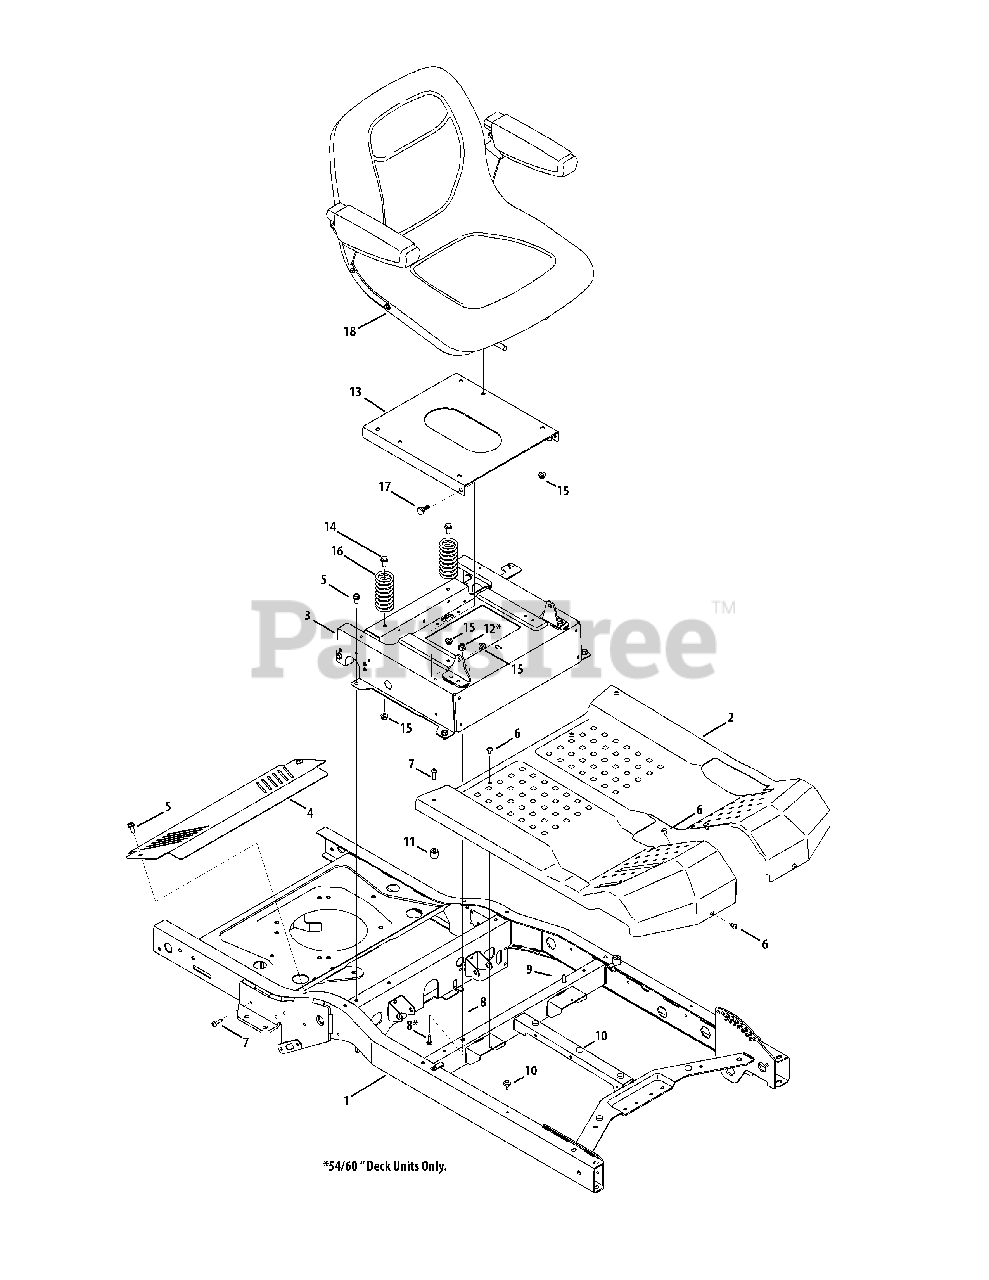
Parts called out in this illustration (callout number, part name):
1	Frame Assembly (46" & 48" Decks)
1	Frame Assembly (54" & 60" Decks)
3	Seat Box Assembly
4	Transmission Cover
5	Hex Washer Screw, 5/16-18 x .750
6	Screw, 1/4-20 x .5
7	Screw, 1/4-20 x 1.0
8	Hex Screw, 1/4-20 x .75
9	Speed Nut, U-Type 1/4-20
10	Rubber Bumper
11	Spacer, .281 x .750 x .680
12	Flange Lock Nut, 1/4-20 (54/60" Deck Units only)
13	Seat Base
14	Hex Washer Screw, 5/16-18
15	Flange Lock Nut, 5/16-18
16	Comp. Spring, 1.71 x 3.735 x .238
17	Shoulder Screw, 5/16-18 x .437 x .268
18	Seat w/ Armrests
